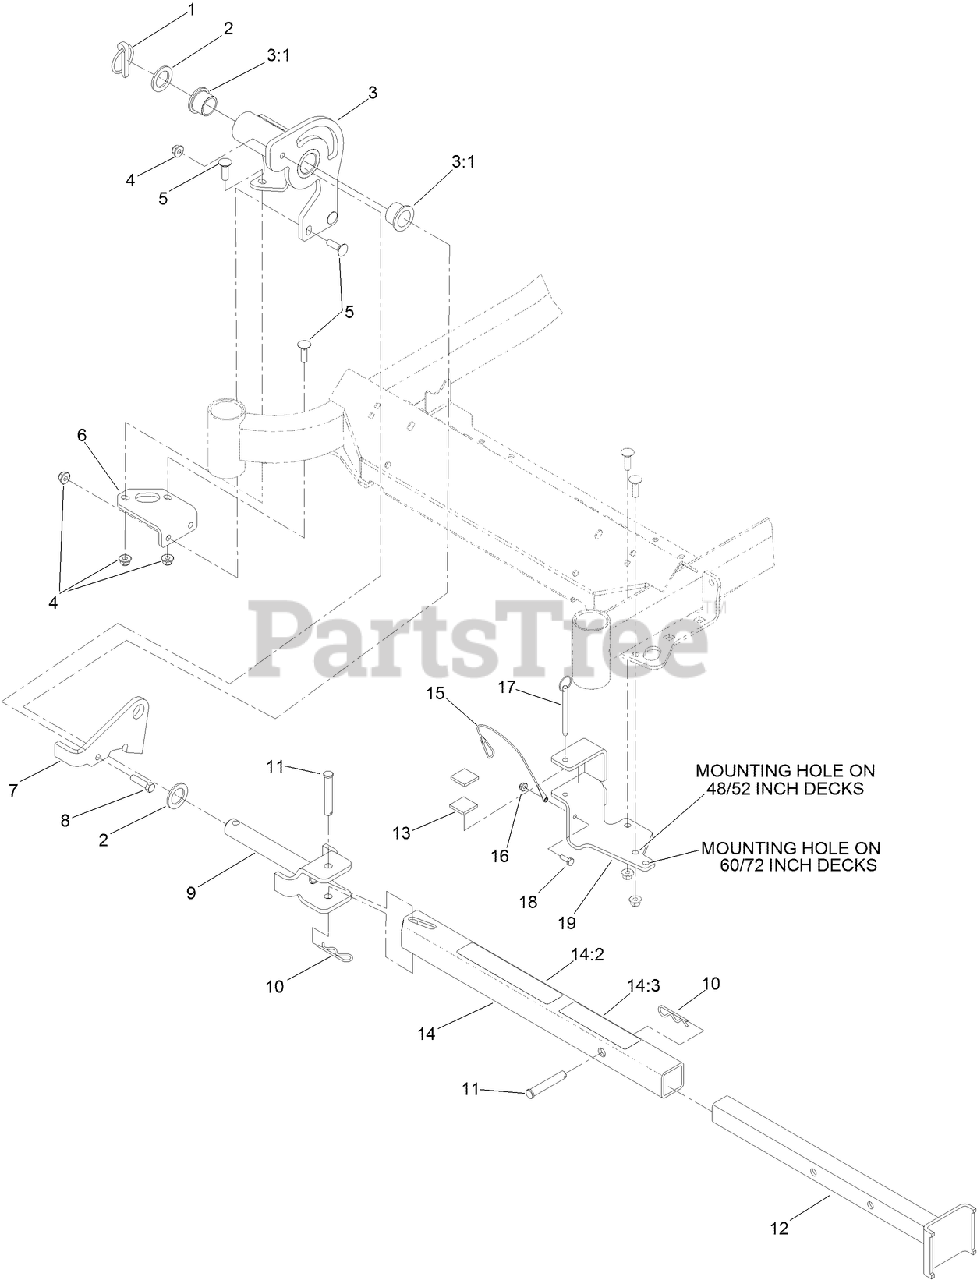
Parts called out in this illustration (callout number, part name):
1	PIN-LYNCH
2	WASHER-THRUST
3	PIVOT PLATE ASM
3:1	BUSHING
4	NUT-HF, NI
5	BOLT-CARR
6	BRACKET-MOUNT, PIVOT
7	PLATE-LATCH
8	SCREW-HH
9	PIN-PIVOT
10	PIN-HAIR
11	PIN-CLEVIS
12	TUBE-INNER
13	CUSHION-RUBBER
14	OUTER TUBE ASM
14:2	DECAL-Z STAND
14:3	DECAL-WARNING
15	LANYARD-NYLON
16	NUT-HF
17	PIN-HITCH, COTTERLESS
18	SCREW-HH
19	CRADLE-Z STAND
